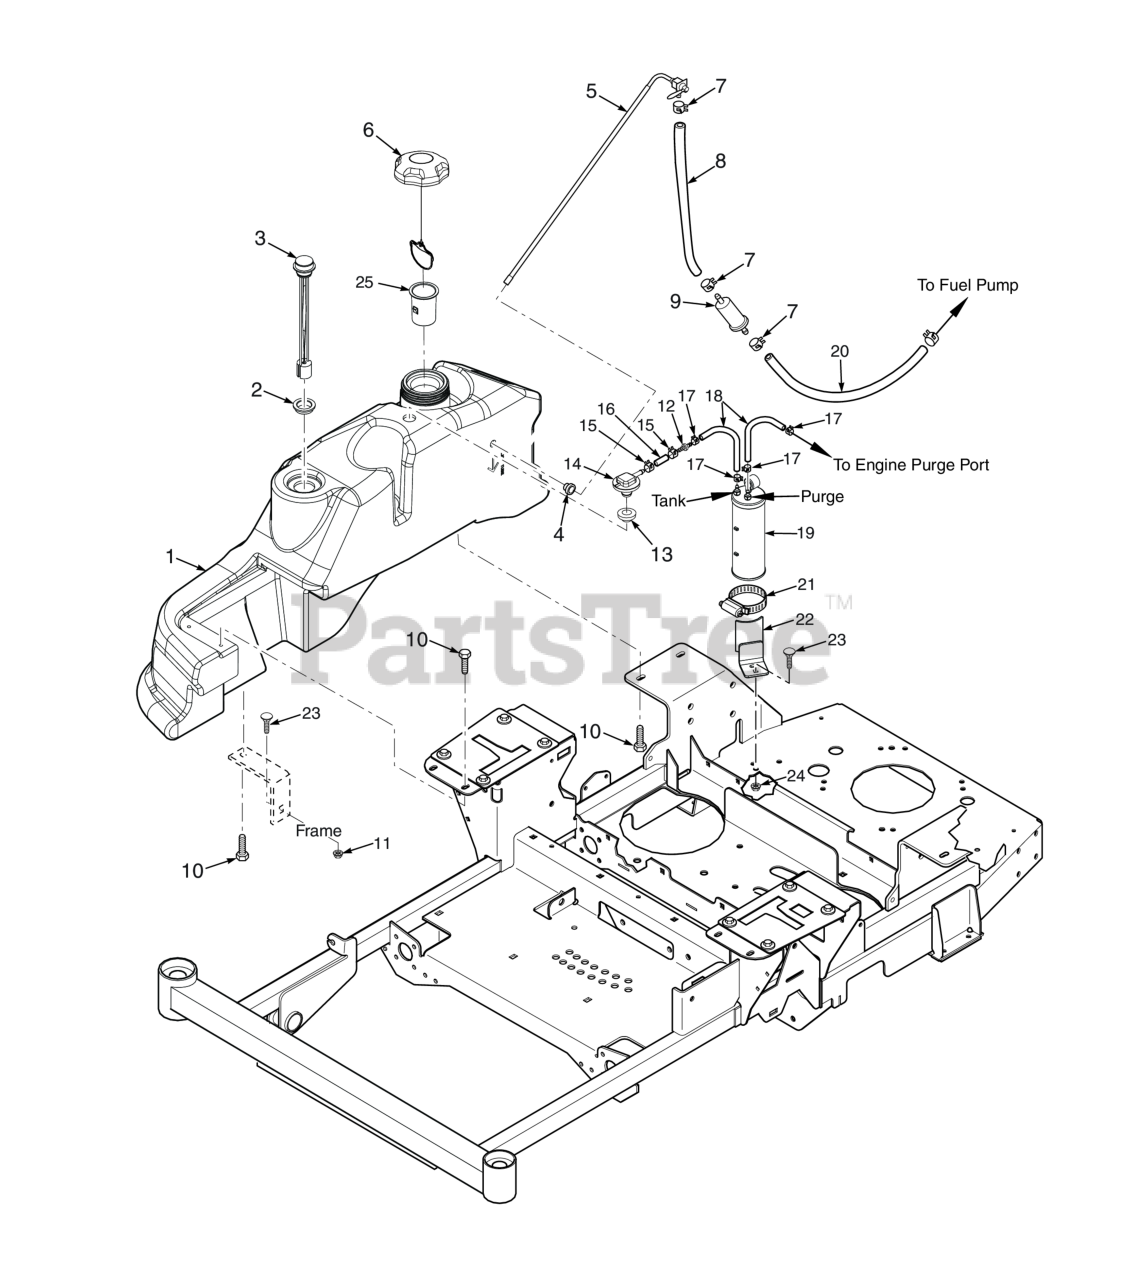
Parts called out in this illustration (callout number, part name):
1	Fuel Tank Assembly - SPZ
2	Grommet, Fuel Gauge
3	Fuel Gauge Assembly
4	Bushing, 0.56" Dia. Viton
5	Fuel Tube Assembly
6	Fuel Cap w/ Tether (E.P.A.)
7	Clamp, Fuel Hose 1/4" Hose I.D.
8	Fuel Hose, 1/4" I.D. Non-Perm (791DFI Fuel Return) - Order by Inch
9	Battery, 350 CCA
10	Capscrew, 5/16-18 x .75 Serrated Flange Hex Head
11	Nut, Flange Head Elastic Stop 5/16-18
12	Mender, 1/4 x 3/16 w/0.02 Hole
13	Grommet, Viton,
14	Remote Vent, No Valve
15	CLAMP, FUEL HOSE(KAWASAKI ONLY)
16	Hose, 1/4" Vapor Recovery (order by inch)
17	Clamp, Vapor Recovery Hose 3/16"
18	Hose, Vapor Recovery 3/16" (order by inch)
19	Carbon Canister - SVR-52V / SVR-61V
20	Battery, 350 CCA
21	Clamp, 3-1/2" Max. Dia.
22	Bracket Weldment - SPZ61H
23	Bolt, 5/16-18 x .75 RHSN Carriage
24	Nut, Serrated Flange 5/16-18 (Right Front Engine Mounting, Briggs and Kohler Only)
25	Tube, Fuel Tank Insert - 4"
